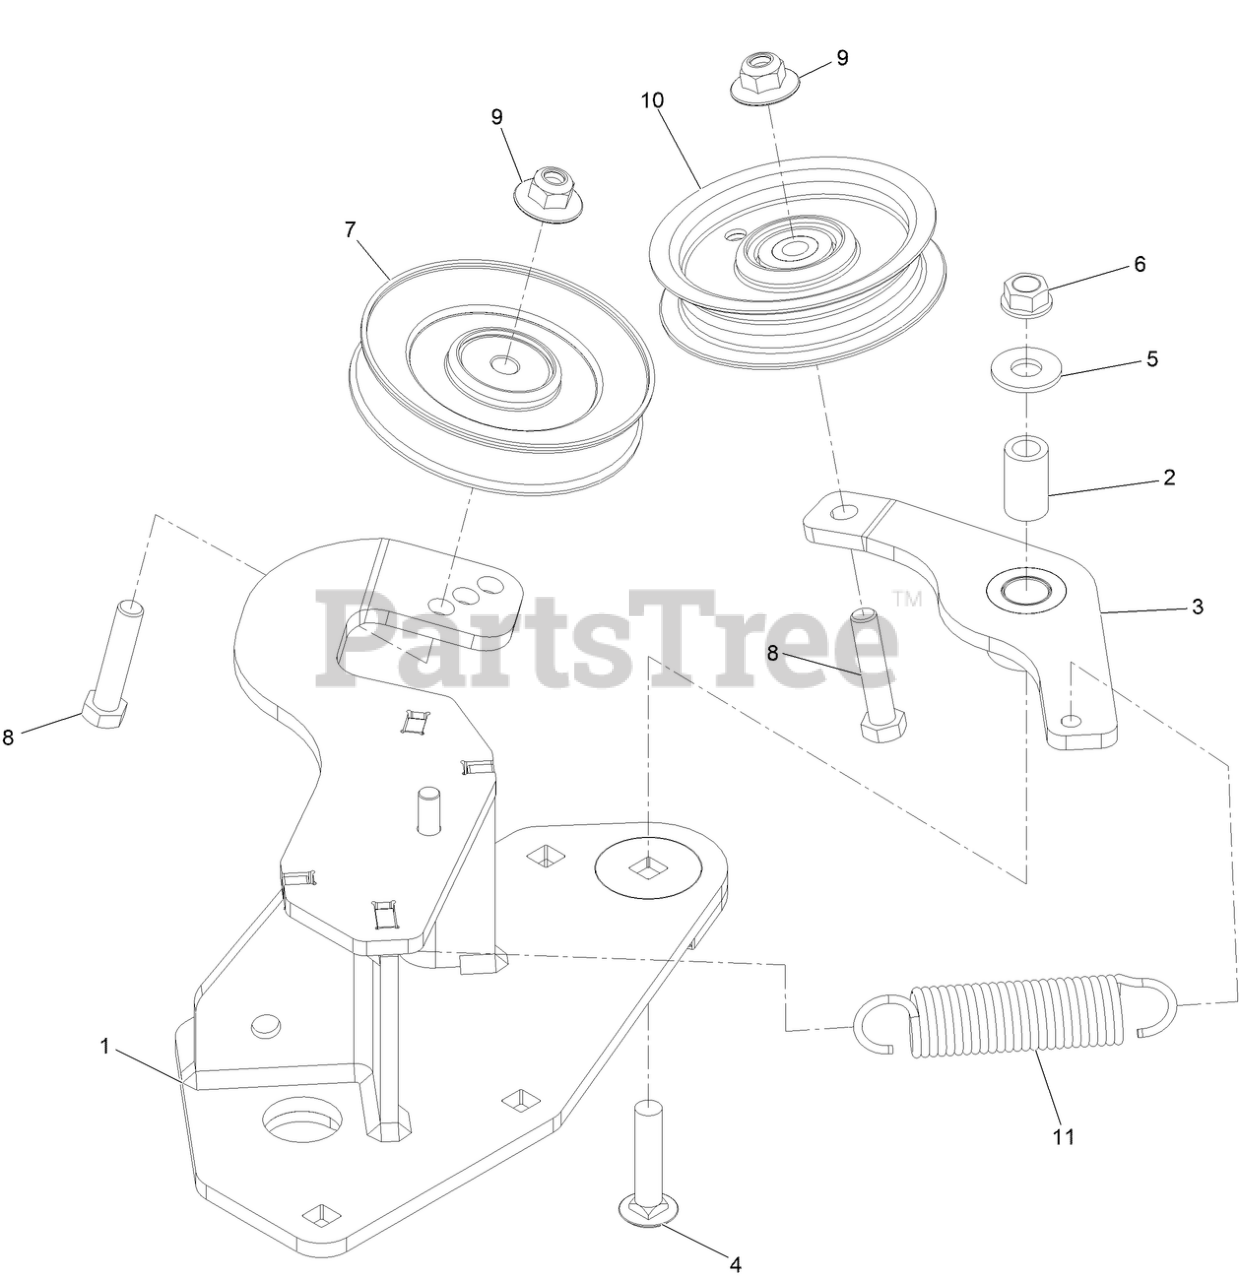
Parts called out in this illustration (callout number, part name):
1	Idler ASM-Blower [black]
2	BUSHING-PIVOT, IDLER
3	IDLER ASM
4	SCREW-CARR
5	WASHER-FLAT
6	NUT-HHF, WHIZ
7	PULLEY-IDLER
8	SCREW-HH
9	Nut-Nyloc 3/8-16 Flg
10	PULLEY-IDLER, FLAT
11	SPRING-EXTENSION
